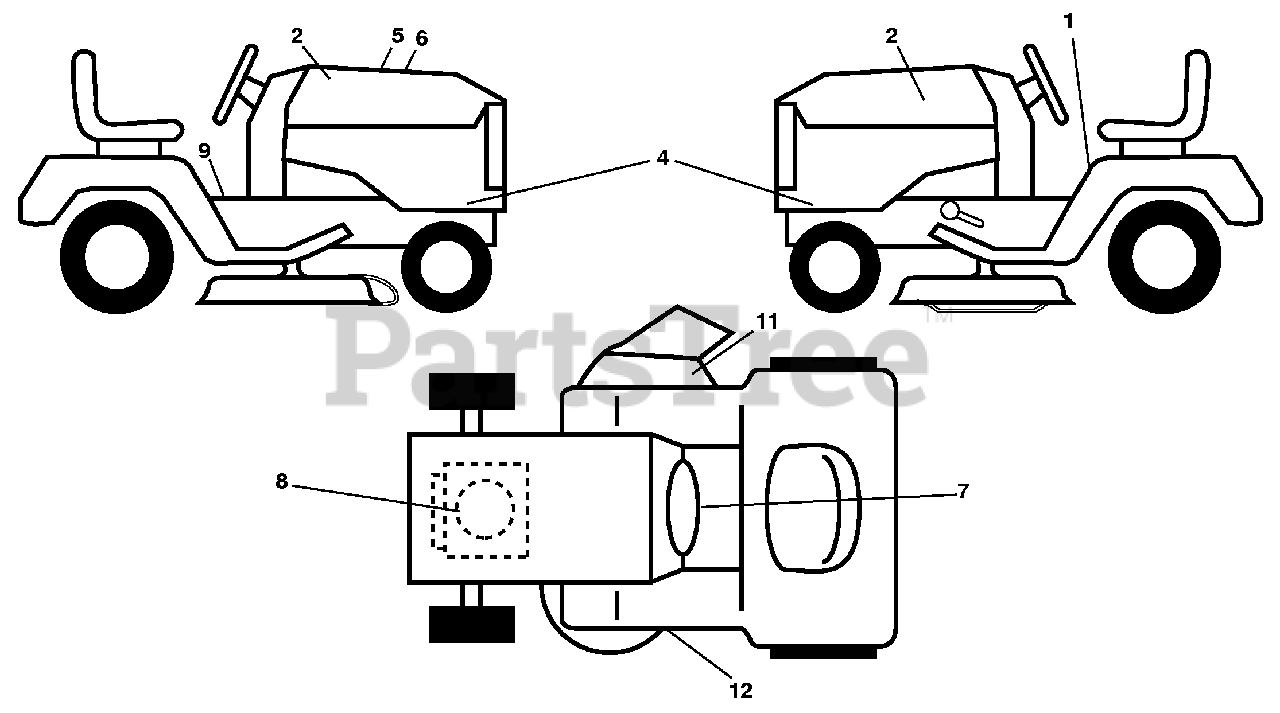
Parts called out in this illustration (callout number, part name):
1	Decal, Fender Warn./Instructions
2	Decal, Hood Logo
4	Decal, Hood Panel
5	Decal, Customer Respons.
6	Decal, Replacement
7	Decal, Warning Spark Arrestor
8	Decal, Engine
9	Decal, Battery Dnge/Poi
11	Decal, Warning
12	Decal, Mower V-Belt Schematic
